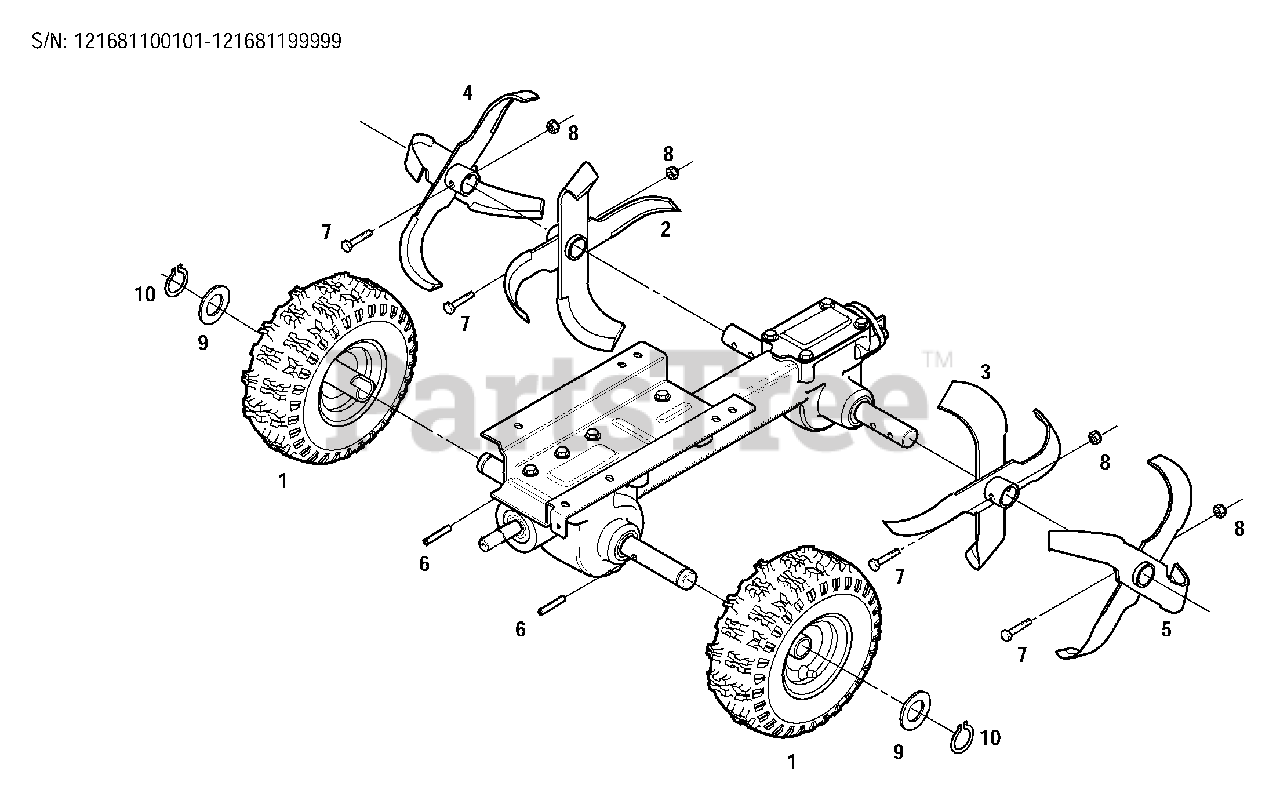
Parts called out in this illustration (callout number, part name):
1	Tire/Wheel Assy
2	Tine Assy, R/H Inside
3	Tine Assy, L/H Inside
4	Tine Assy, R/H Outside
5	Tine Assy, L/H Outside
6	Spring Pin
7	Screw, Hex Head, 5/16-18
8	Nut, Hex Lock, 5/16-18
9	Washer, 1.5 x 1.0 x .060
10	Retaining Ring, External, .906
